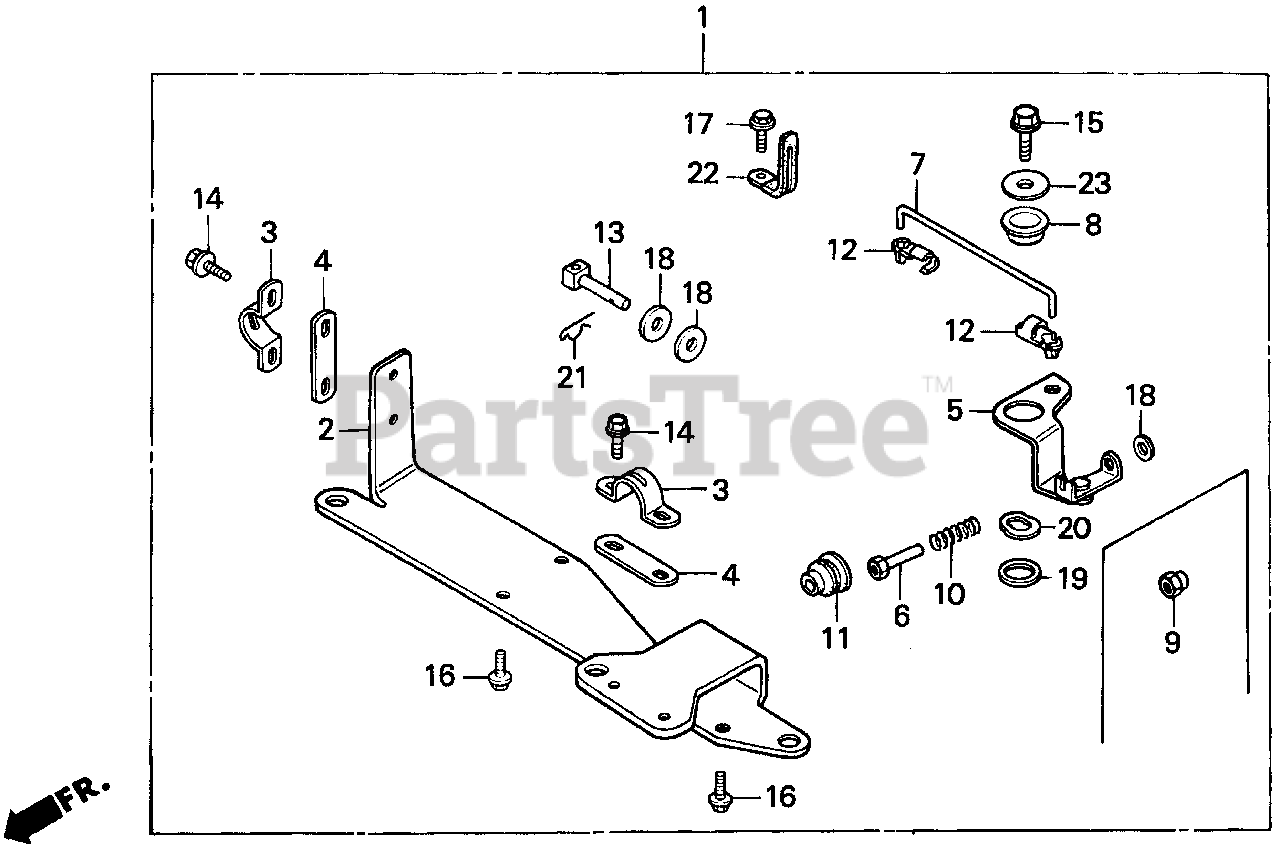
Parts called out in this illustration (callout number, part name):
1	CONTROL KIT, REMOTE
2	BRACKET, STEERING
5	LEVER, CONTROL
6	NUT B, CONTROL ADJUSTING
7	ROD, CONTROL
8	BUSH, CONTROL LEVER
9	NUT A, CONTROL ADJUSTING
10	SPRING, CONTROL LEVER
11	GROMMET, CONTROL CABLE
12	BUSH, LINKAGE
13	PIVOT, SHIFT
14	BOLT, FLANGE (5X10)
15	BOLT, FLANGE (6X12)
16	BOLT, FLANGE (6X14)
17	BOLT, FLANGE (5X10)
18	WASHER, PLAIN (5MM)
19	WASHER (14MM)
20	WASHER, WAVE (14MM)
21	PIN, LOCK (5MM)
22	CLIP, WIRE
23	WASHER, PLAIN (6MM)
